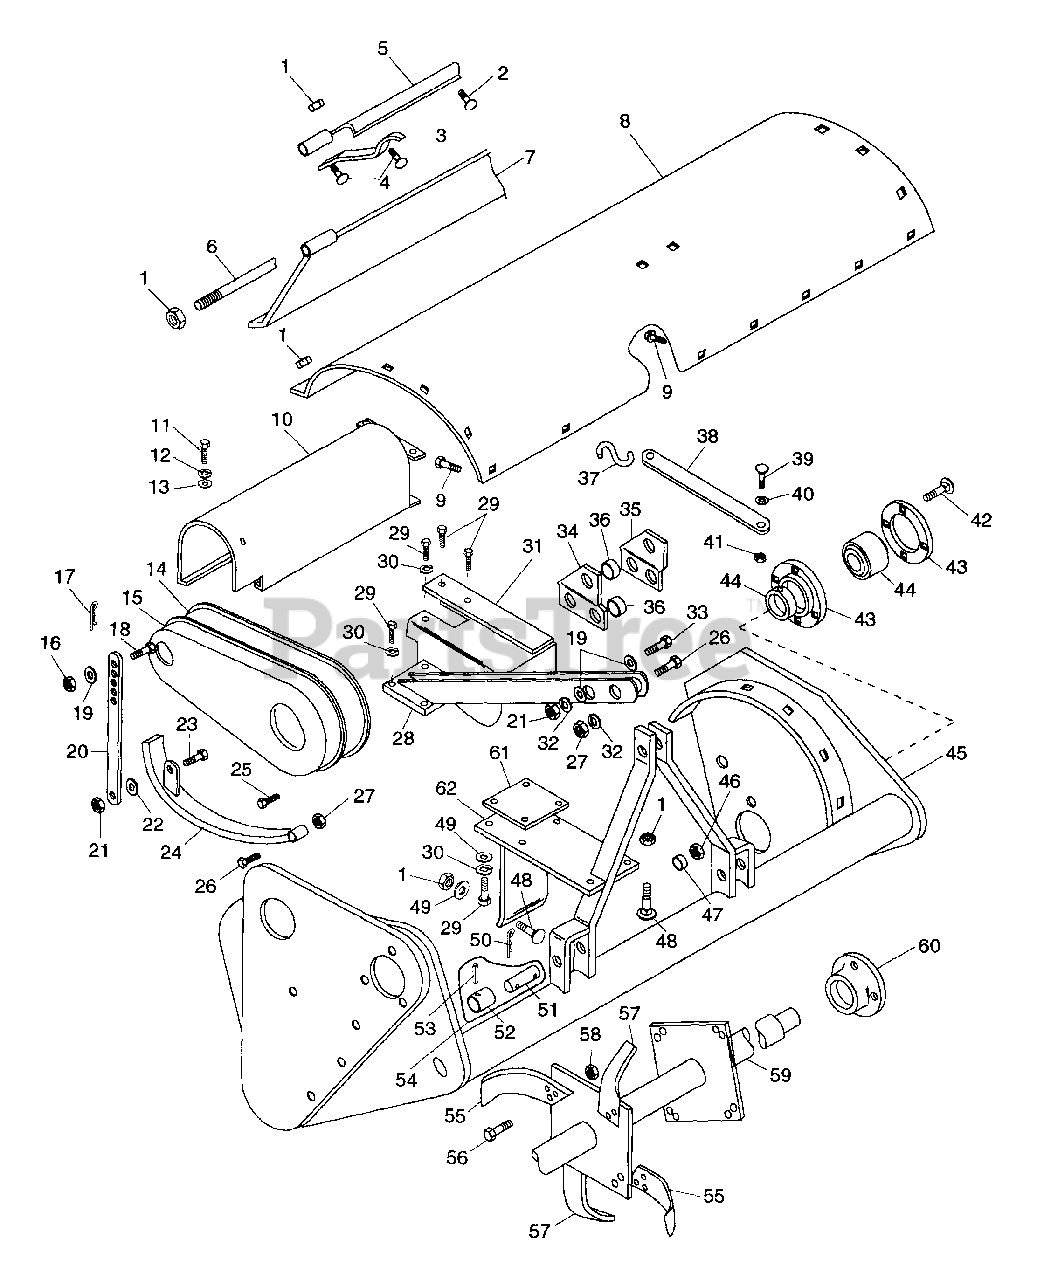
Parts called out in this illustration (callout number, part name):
1	NUT-LK TOP .375-16 GR C YWZC
2	BLT-RDHDSQNK .375-16X.75 GR5PL
4	BLT-RDHDSQNK .38-16X1.25 GR5PL
5	HINGE BRACKET
6	ROD-HINGE
7	LEVEL BLADE
8	SHROUD W/DECALS
9	SCR-TAP .312-18X.75 HWHPLDFGT
10	TUNNEL SHIELD
11	BLT-HEX .31-18X.50 PL GR2
12	WSHR-LK .313X.078 PL MED
13	WSHR-FL-STL.312X.734X.065PL
15	OUTER SHIELD
16	NUT-HEX .625-11
17	PIN-HAIR EXT .12X.31X2.37 PL
18	HEX BOLT-.62-11 X 1.50 SPECIAL
19	WSHR-FL-STL .505X1.000X.062
20	ADJUST STRAP
21	NUT-LK-CROWN .50-13 GR C PL
22	RUBBER WASHER
23	BLT-HEX .50-13X1.50 PL GR2
25	SCR-TAP .312-18X.50 HWH PL 1A
26	BLT-HEX .62-11X2.50 PL GR5
27	NUT-HEX .625-11
28	UPPER LINK
29	BLT-HEX .38-16X1.25 PL GR5
30	WSHR-LK .375X.115 HVY PL
31	PTO SHIELD
32	WSHR-LK .563X.141 MED PL
33	BLT-HEX .50-13X3.25 GR5
34	BRACKET RH
35	BRACKET LH
36	SPACER .630X.875X.625
38	RUBBER STRAP
39	SCR-MCH .25-20X1.25 SLRH PL
40	WSHR-FL-STL .250X.562X.049 PL
41	NUT-HEX .250-20 PL
42	BLT-RDHDSQNK .50-13X1.75 PL
43	FLANGETTE-4 HOLE
44	BRG-BALL 1.50X80MMX1.7
46	NUT .50-13 PL
47	SPACER .510X.750X.312
48	BLT-RDHDSQNK .38-16X1.0 GR5PL
49	WSHR-FL-STL .38X.875X.083 PL
50	PIN-HAIR INT .14X.4X2.75
52	SPACER .635X.875X1.370
53	PIN-ROLL .250X3.00
54	PIN ASSEMBLY
55	TINE RH
56	BLT-HEX .38-16X1.13 GR9
57	TINE LH
58	NUT-LK-FLG .375-16 PL
59	TINE SHAFT
60	CAP-BEARING GUARD
61	SPACER PLATE
62	GEAR BOX MOUNT
